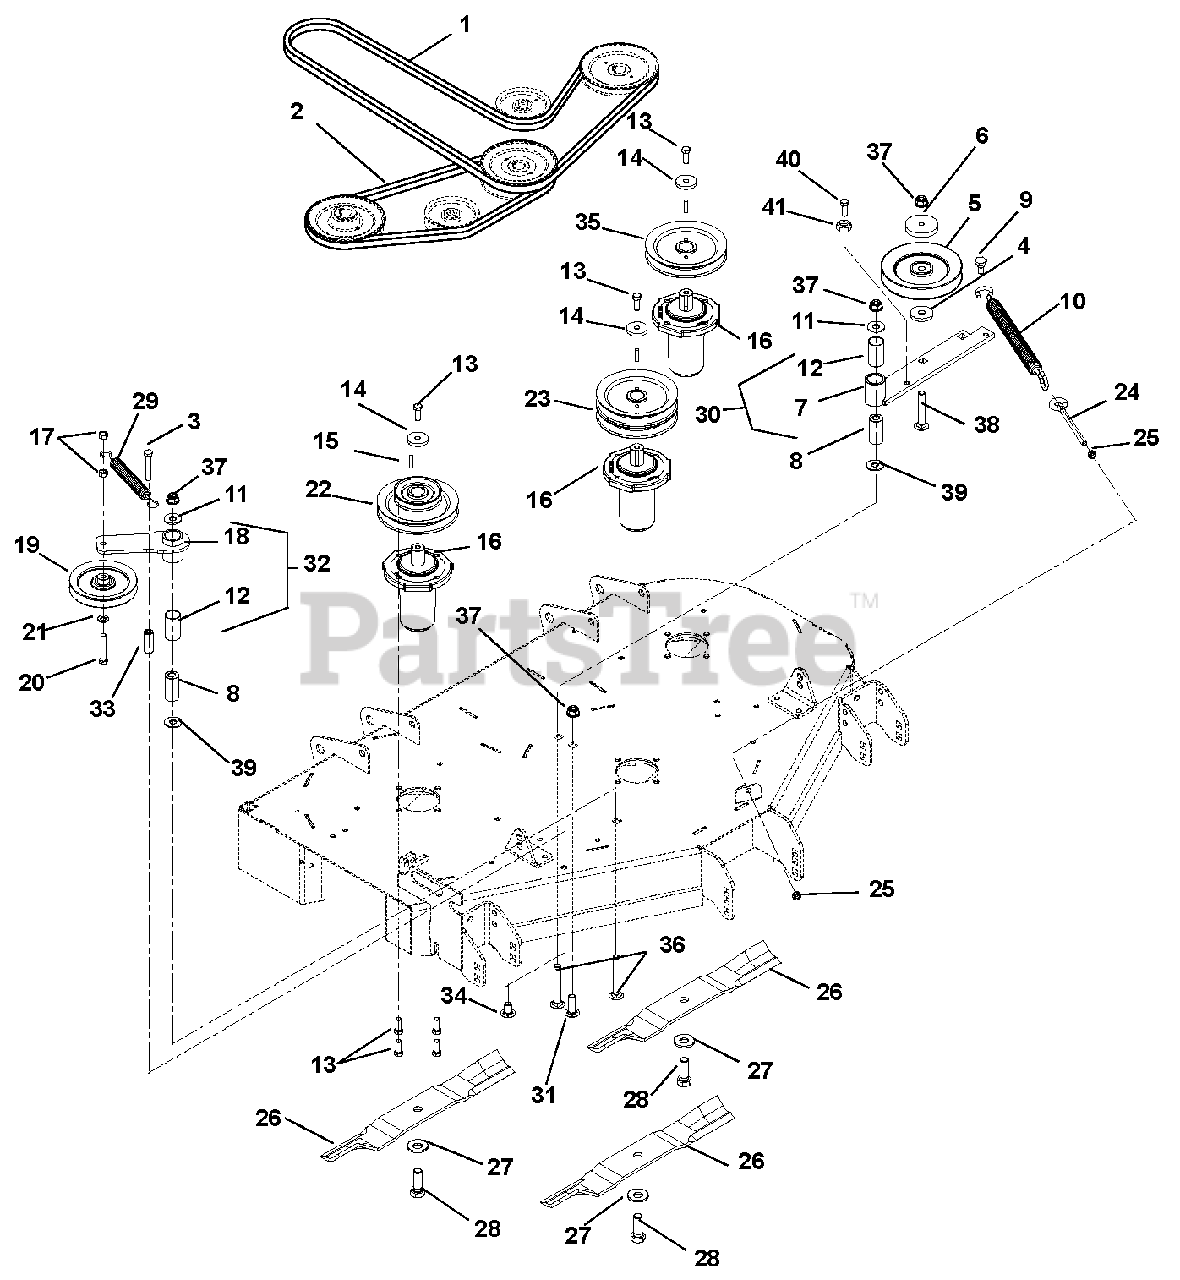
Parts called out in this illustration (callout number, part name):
1	Belt, BB 120.50 Wrapped Hex (PTO Belt)
2	Belt, B 51.18 Raw Cogged (Deck Belt)
3	Bolt, Hex .38-16 x 1.50 Grade 5
4	Bushing, Spacer .502 x .997 x .50
5	Sheave, .50" ID x 6.00" OD V-Idler
6	Cap, Idler Bearing Sealing
7	Idler Pivot Arm Weldment – Black
8	Bushing, Spacer .505/.500 x .999/.996 x 2.05/2.03
9	Bolt, Shoulder EP .38-16 x .30 Hex
10	Spring, Extension (PTO Deck Idler)
11	Washer, Flat Steel .531 x 1.25 x .100
12	Bushing, 1.00 x 1.125 x 1.936
13	Bolt, Hex .38-16 x 1.00
14	Washer, Flat Steel .406 x 1.50 x .245
15	Key, Square .25 x .25 x 1 RC 40-50
16	Spindle Assembly
17	Nut, Locking, Center .38-16
18	Idler, Pivot Arm
19	Sheave, .38" ID x 5" OD V-Idler
20	Bolt, Hex .38-16 x 2.25
21	Washer, Flat Steel .406 x .812 x .065
22	Pulley, Double 1" ID x 5.75" & 3.50" OD
23	Pulley, Double 1" ID x 5.75" OD
24	Bolt, .38-16 x 4.00 .62 Diameter Eye
25	Nut, Hex, Jam .375-16
26	Blade, 16.19" Mower
27	Washer, Bellville .63 x 1.625 x.14
28	Bolt, Hex .62-18 x 1.75 Grade 8
29	Spring, Extension (Deck Belt Idler)
30	Assembly, PTO Idler Pivot Arm (Includes item 7 and item 12)
31	Bolt, Round Head Square Neck .50-13 x 1.5, Full Thread, Grade 5
32	Assembly, Idler Pivot Arm (Includes item 12 and item 18)
33	Nut, Coupling .375-16 x 1.75
34	Bolt, Round Head Square Neck .38-16 x 1.00
35	Sheave, Single 1.0" ID x 5.75" OD
36	Bolt, Round Head Square Neck .50-13 x 3.50
37	Nut .50-13 Nyloc Flange
38	Bolt, Round Head Square Neck .50-13 x 3.00 Grade 5
39	Washer, Flat .640 x 1.75 x .250
40	Bolt, Hex .38-16 x 2.75 Grade 5
41	Nut, Hex .38-16
